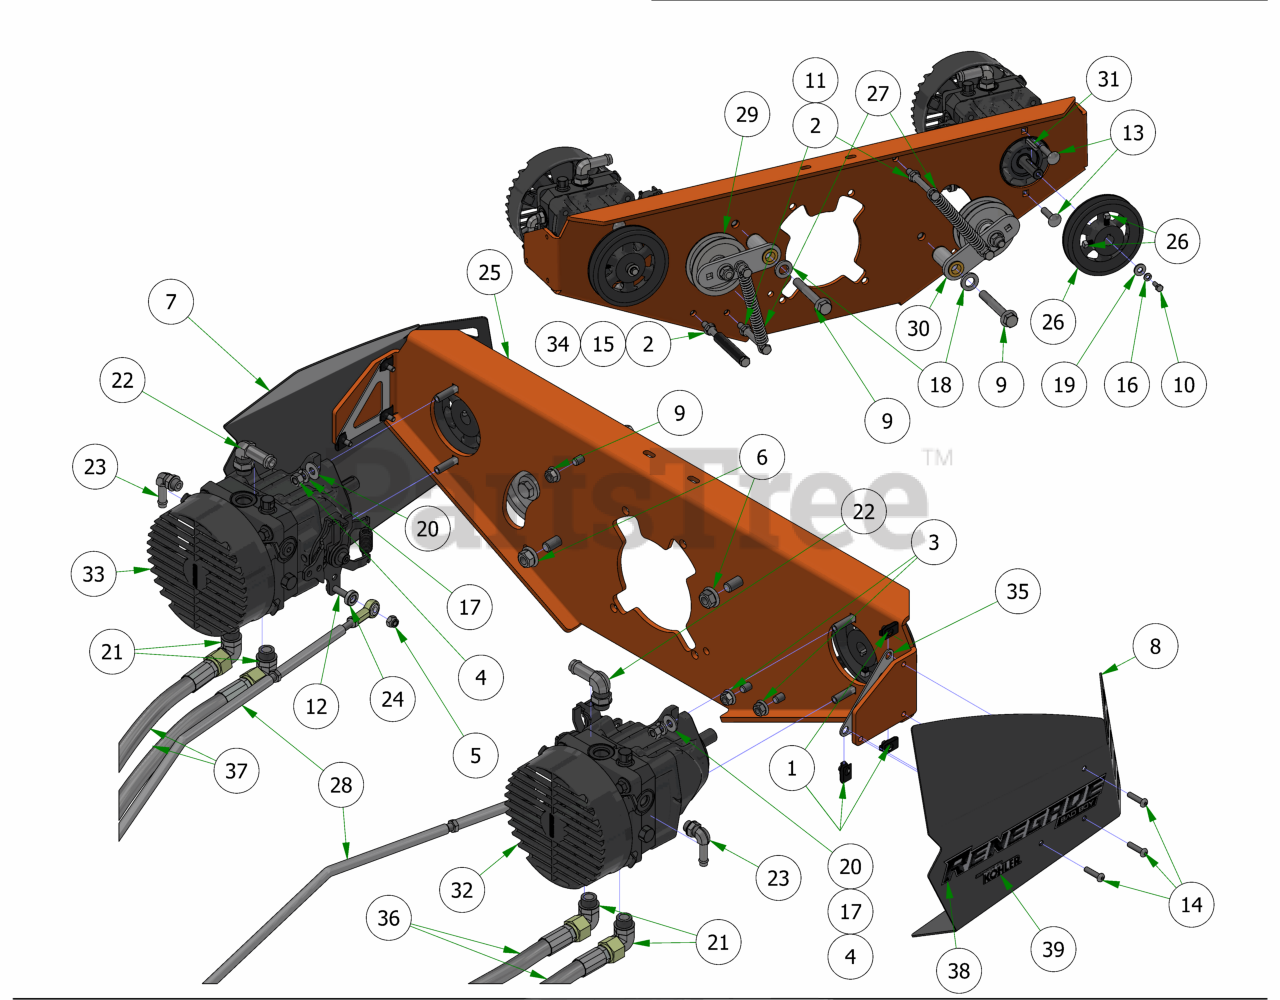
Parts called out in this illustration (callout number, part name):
1	1/4-20 Cage Nut
2	3/8-16 HEX SERRATED FLANGE NUT HARD/ZINC
3	3/8-16 NYLON INSERT FLANGE LOCKNUT (GR.F) ZINC
4	3/8-16 HEX NUT ZINC
5	5/16-18 NYL INS L/N ZC
6	1/2-13 NYLON INSERT FLANGE LOCKNUT ZINC
7	2019 Horizontal Pump Cover - Right - Black
8	2019 Horizontal Pump Cover - Left - Black
9	1/2-13 X 90MM HEX FLANGE BOLT W/SHOULDER (GR.8) ZINC
10	M6-1.0 X 16MM DIN 933 HEX TAP BOLT (CL 8.8) ZINC
11	3/8-16 X 3-1/2 HEX CAP SCREW (GR.5) ZINC
12	5/16-18 X 1-1/4 HEX C/S (GR.5) ZC
13	3/8-16 X 1-1/2 CARRIAGE BOLT ZINC
14	1/4-20 x 1" BS C/S 18-8 SS
15	3/8-16 X 5-1/2 HEX CAP SCREW (GR.5) ZINC
16	1/4 SPLIT LOCKWASHER ZINC
17	3/8 SPLIT LOCKWASHER ZINC
18	.635 ID X 1.120 OD X .140 THICK FLAT WASHER NYLON
19	1/4 USS FLAT WASHER (3/4 OD) ZINC
20	5/16 USS FLAT WASHER (7/8 OD) ZINC
21	2019 Outlaw 90 Degree Pump Fitting #6801-10-08
22	90 Degree Fitting, 1/2 x 3/4, 4601-8-8
23	90 Degree Fitting, 3/8 s 9/16
24	ACS Spacer 3/4x3/8x1/4
25	Pump Plate - 2019 Horizontal Gas-Orange
26	5" PUMP PULLEY W/ SET SCREW
27	ZT and ACS Handle Spring
28	2019 Renegade Push Rod Assembly
29	2019 Renegade Belt Tensioner LH
30	2019 Renegade Pump Belt Tensioner RH
31	5MM X 36MM SQ MACHINERY KEY C1018 ROUNDED ENDS
32	2019 Rogue/Renegade Left Pump 16cc
33	2019 Outlaw Renegade Right Pump 16cc
34	3/8 hose 4" long
35	Pump Plate Clip Nut Holder
36	2019 Renegade Trailing LH Arm Assy
37	2019 Renegade Trailing RH Arm Assy
38	Renegade Back Plate Decal
39	2022 Powered By Kohler Decal
